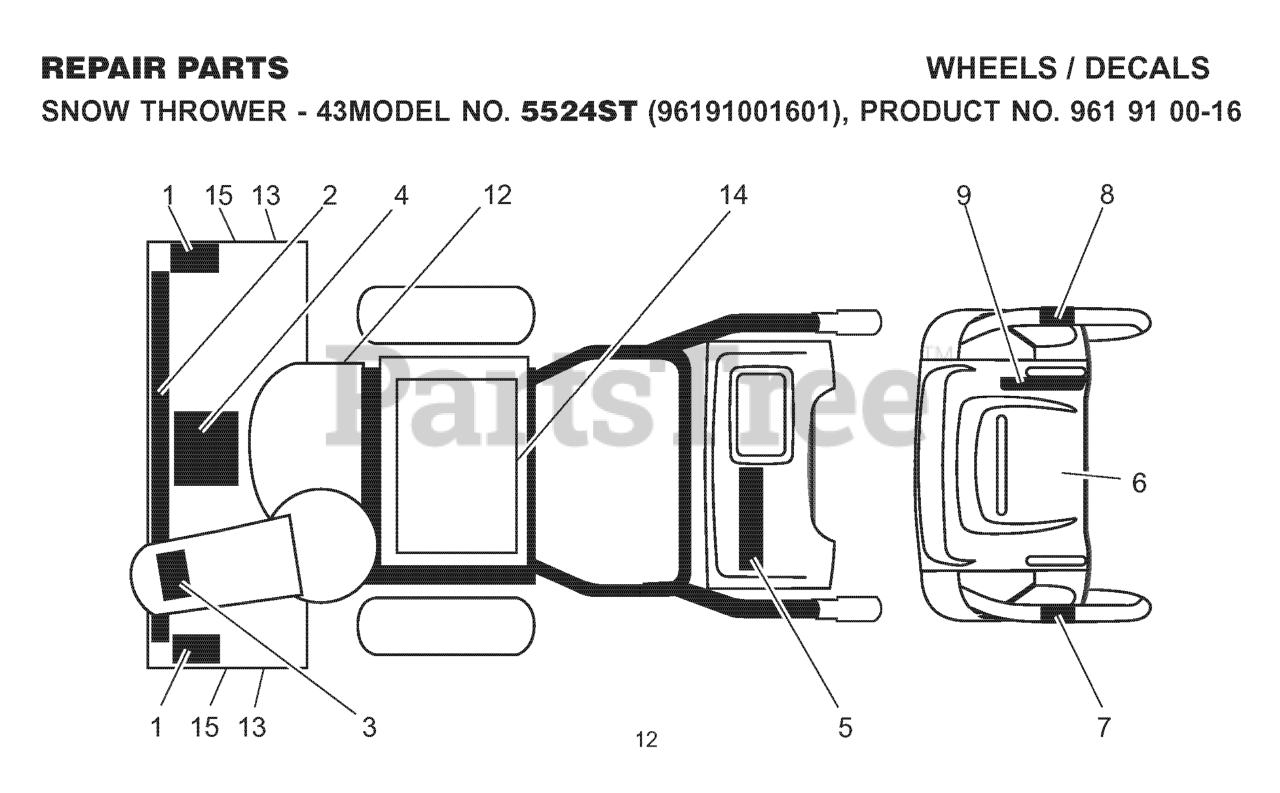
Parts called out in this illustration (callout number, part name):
1	WIRE ASM INNER W/ PLUNGER LT
2	SHAFT ASM R HANDLE
3	PIN GROOVE.
4	RETAINING RING LT
6	BEARING.NYLON
7	GRIP HANDLE
8	PLUNGER BUT KIT
11	LINK LIFT LH
12	LINK LIFT RH
13	RETAINER-SPRNG RB
15	FRONT LINK
16	NUT.HEX.JAM.1/2-13
17	TRUNION
18	NUT LTV
19	ARM.REAR.SUSPENSION
20	SPRING RETAINER
25	SPRING**
26	COTTER PIN
27	ROD ADJ LIFT
28	NUT
29	KNOB INF 3/8-16
31	BEARING PIVOT
32	NUT CROWNLOCK 3/8-24
36	POINTER, HEIGHT INDICATOR(2 2)
38	SCREW.THDROL.5/16-18X3/4.TTY
41	IND. HEIGHT STLT
49	NUT
50	NUT PUSH M
